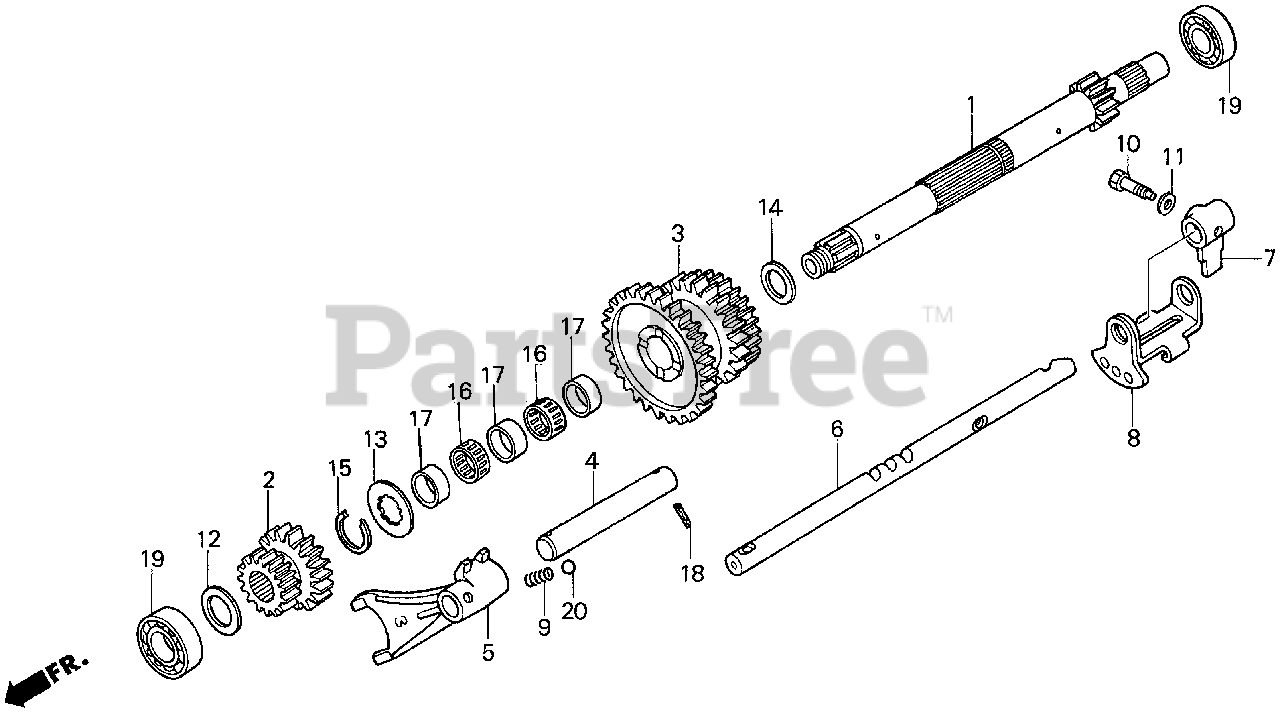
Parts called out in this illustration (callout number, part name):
2	GEAR, THIRD-FOURTH CHANGE
3	GEAR, FIRST IDLE (41T-31T-27T)
4	SHAFT, MAIN CHANGE
5	FORK, SHIFT (3-4)
6	SHAFT, SHIFT PIECE
7	PIECE, SHIFT
8	PLATE, INTERLOCK
9	SPRING A, BALL SETTING
10	BOLT, HEX. (8X24)
11	WASHER, CONICAL SPRING (8MM)
12	WASHER, THRUST (20X31.5)
13	WASHER, SPLINE (23MM)
14	WASHER, THRUST (24X36)
15	CIRCLIP (OUTER) (23MM)
16	BEARING, NEEDLE (24X28X13) (TOMUSON)
17	COLLAR A, FIRST IDLE GEAR
18	PIN, SPRING (3X18)
19	BEARING, RADIAL BALL (6204)
20	BALL, STEEL (#10) (5/16)
